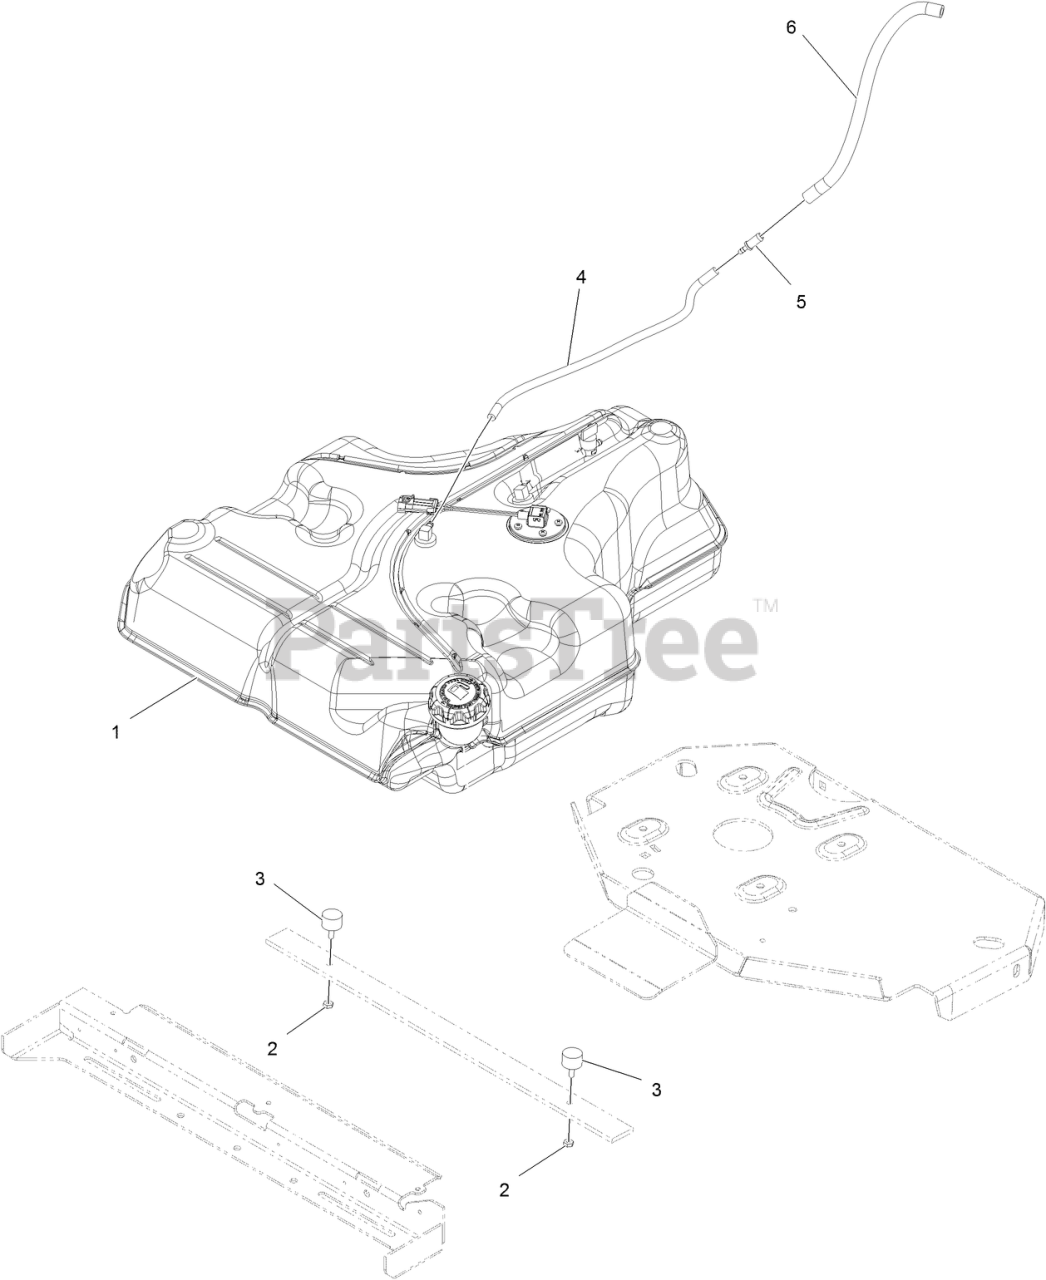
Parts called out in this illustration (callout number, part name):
1	FUEL TANK ASM
2	NUT-JAM
3	BUMPER
4	HOSE-FUEL
5	FITTING-STRAIGHT
6	HOSE-FUEL
